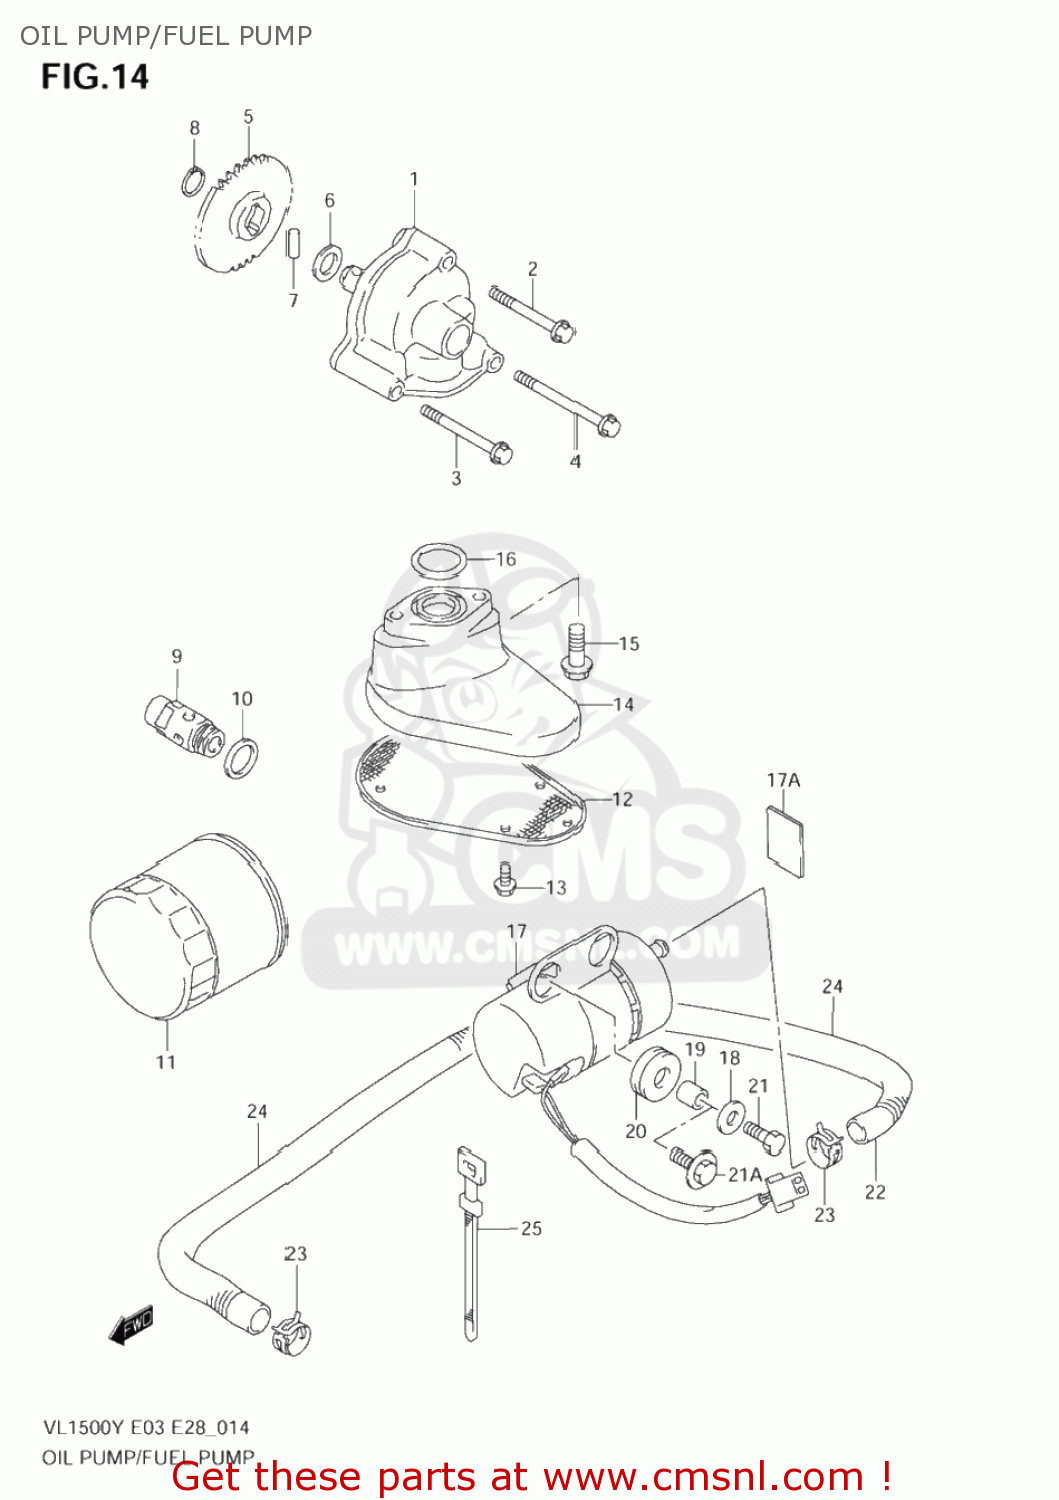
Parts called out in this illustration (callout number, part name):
1	PUMP ASSY,ENGINE OIL
2	BOLT
3	BOLT
4	BOLT
5	GEAR,OIL PUMP DRIVEN
6	SHIM(12X20X0.5)
7	PIN(5X18)
8	CIRCLIP,12 MM
9	VALVE ASSY,OIL RELIEF
10	GASKET(16X22X2) (NAS)
11	FILTER ASSY,EN
12	STRAINER,ENGINE OIL
13	BOLT
14	HOLDER,OIL STR
15	BOLT
16	O RING(D:3.1,ID:22.7)
17	PUMP ASSY,FUEL
17A	CUSHION,CHAIN CASE
18	WASHER(6.5X20X1.2)
19	SPACER(6.5X9X9)
20	CUSHION
21	BOLT
21A	BOLT 6X20
22	HOSE,FUEL PUMP & CARB
23	CLIP
24	SPRING
25	CLAMP(L:165)
